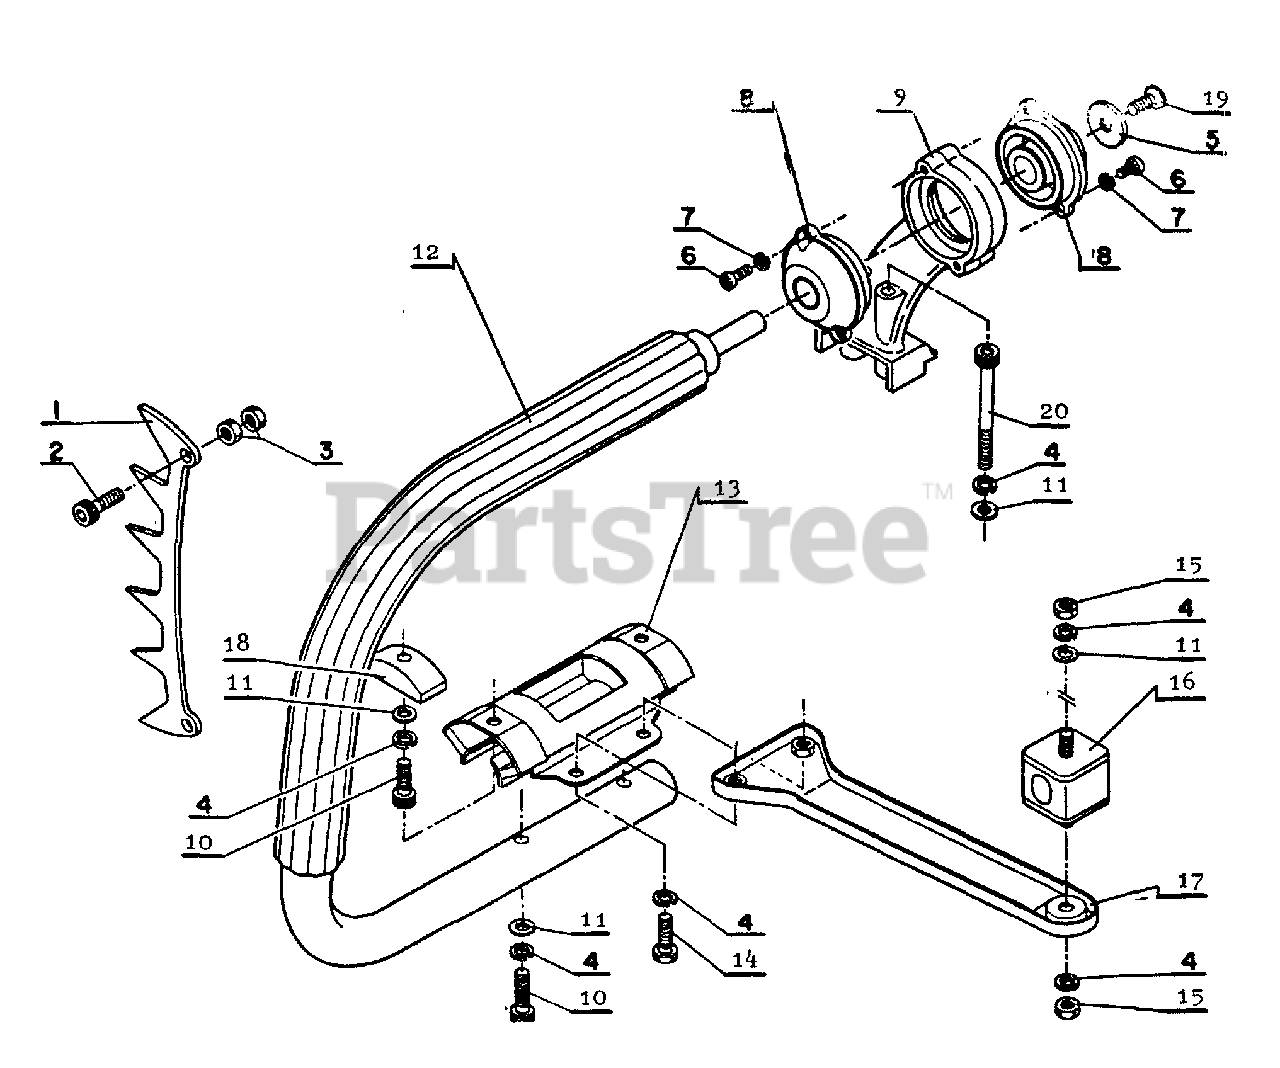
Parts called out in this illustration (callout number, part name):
1	SPIKE
2	SCREW - 5X15
3	NUT - 5
4	LOCKWASHER - 5
5	WASHER
6	SCREW - 3X8
7	LOCKWASHER - 3
8	Cushion rubber (L-U)
9	BRACKET, HANDLE - UPPER
10	SCREW - 5X20
11	WASHER - 5
12	HANDLE - FRONT
13	Cushion rubber (L-L)
14	BOLT - 5X8
15	LOCKNUT - 5
16	Cushion rubber (L-L2)
17	BRACKET, HANDLE - LOWER
18	ADAPTER, CUSHION
19	SCREW - 5X12
20	SCREW - 5X55
